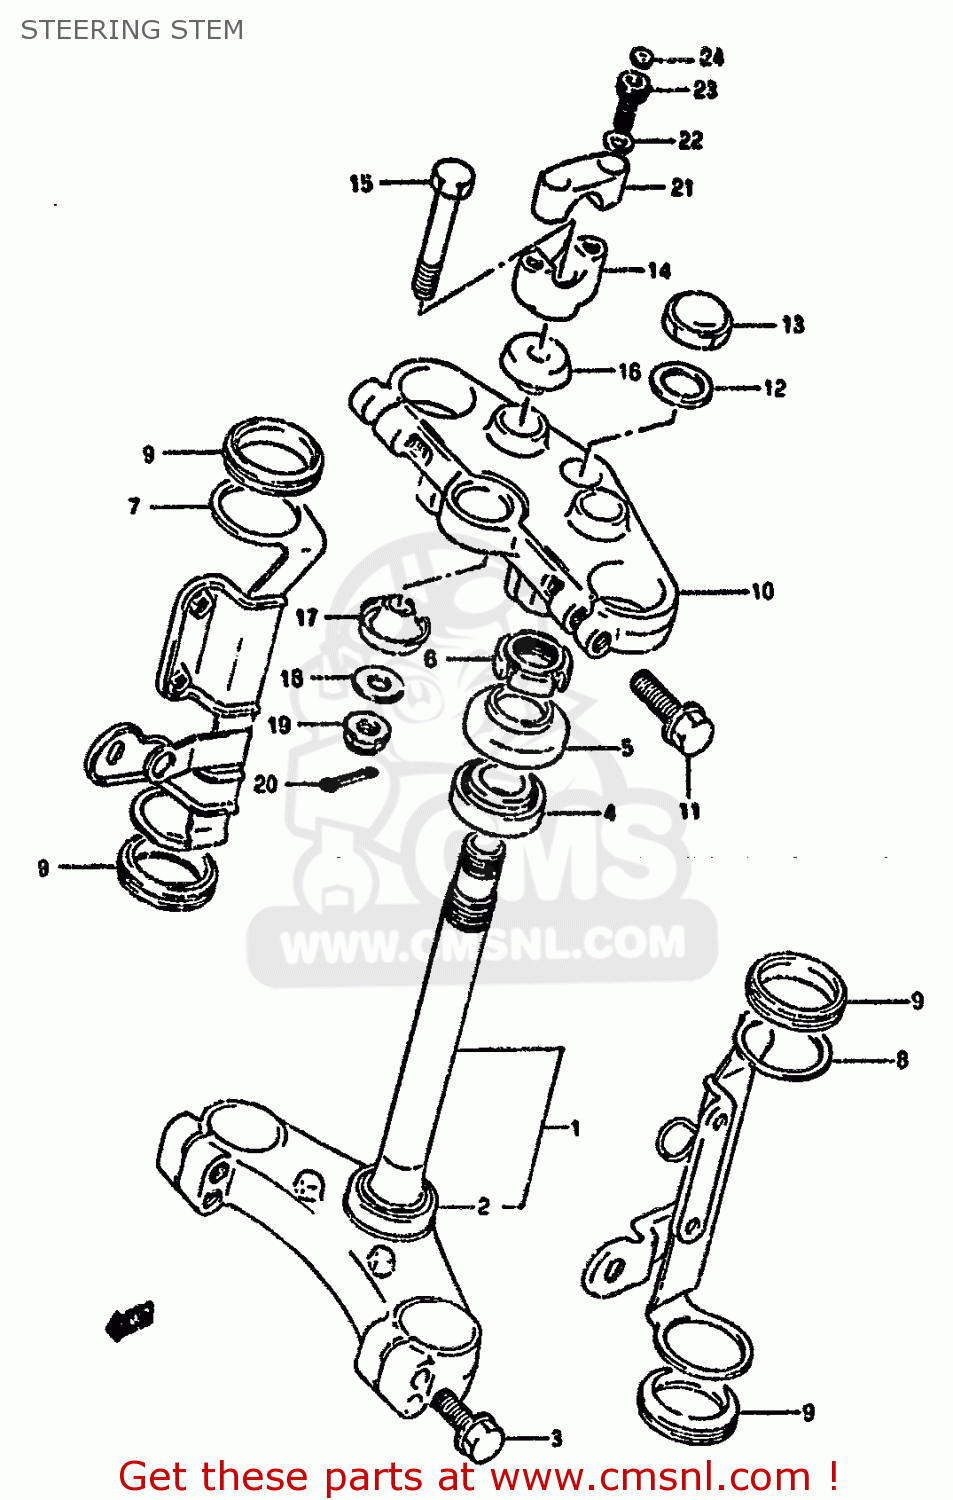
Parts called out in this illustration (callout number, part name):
1	STEM,STEERING
2	BEARING(30X55X17)
3	BOLT 8X40
4	TAPER,ROLLER BEARING
5	SEAL,STEERING UPR DUST
6	NUT,STEERING STEM(25X44X10)
7	BRACKET COMP,HEADLAMP
8	BRACKET,HEADLAMP,LEFT
9	CUSHION,HEADLAMP BRACKET
10	HEAD,STEERING STEM
11	BOLT
12	WASHER(22.5X32X1.6)
13	NUT,CAP
14	HOLDER,HANDLE LWR
15	BOLT
16	RUBBER,DAMPER,UPPER
17	DAMPER,LWR
18	WASHER,HANDLEBAR HOLDER
19	NUT
20	COTTER PIN
21	HOLDER,HANDLE UPR
22	WASHER
23	BOLT
24	CAP(OD:14.5)
